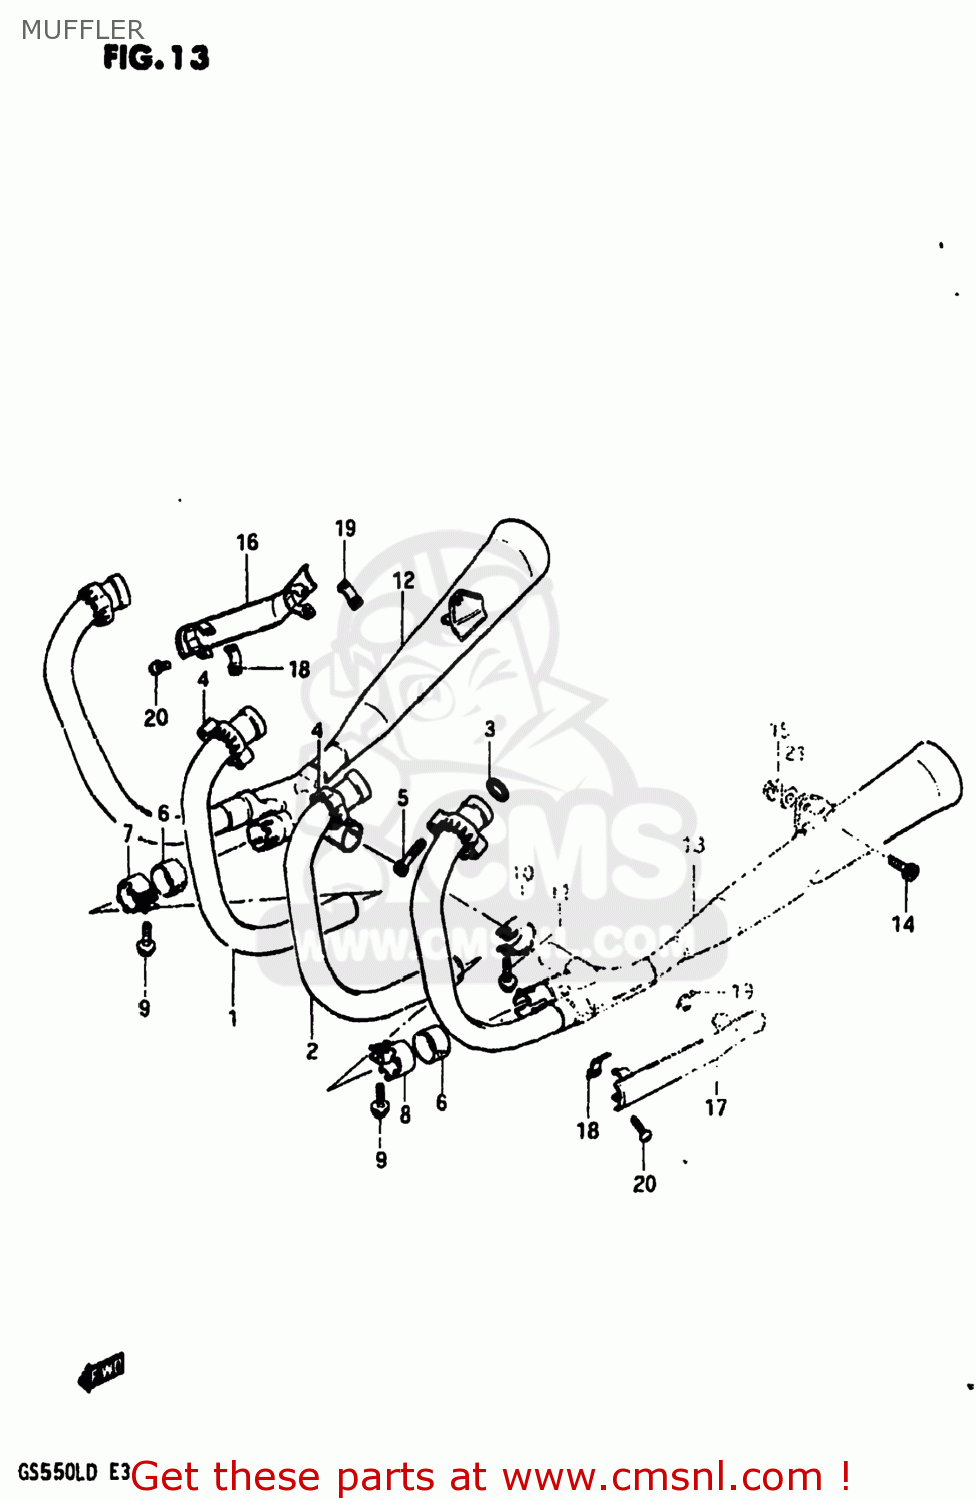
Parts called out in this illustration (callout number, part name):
1	PIPE.EXH.CENTER
2	PIPE,EXHAUST,CENTER,LEFT
3	GASKET,EXHAUST PIPE (NAS)
4	CLAMP,EXHAUST PIPE
5	BOLT
6	CONNECTOR,MUFFLER
7	CLAMP,MUFFLER CONNECTOR,R
8	CLAMP,MUFFLER CONNECTOR,L
9	BOLT
10	CLAMP,EXHAUST
11	BOLT,REAR
12	MUFFLER ASSEMBLY
13	MUFFLER ASSEMBLY
14	BOLT
15	NUT
16	COVER,MUFFLER,RIGHT
17	COVER,MUFFLER,LEFT
18	CLAMP,MUFFLER COVER
19	CLAMP,MUFFLER COVER
20	SCREW
21	WASHER
